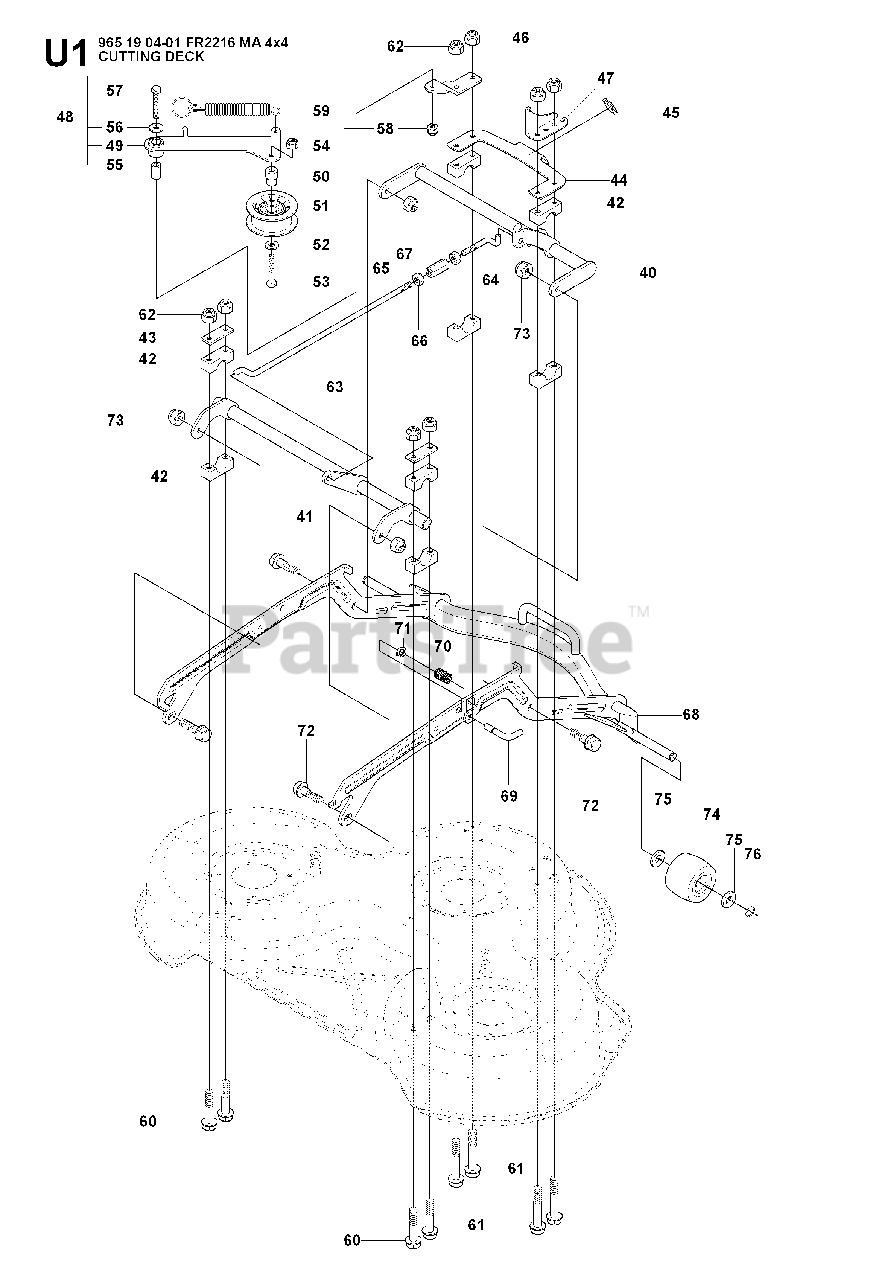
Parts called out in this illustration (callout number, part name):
54	LOCKNUT M8
57	SCREW
58	LOCKNUT M8
62	LOCKNUT M8
73	LOCKNUT M8
74	DECK ROLLER, FRONT
76	RETAINING RING SGA 15
